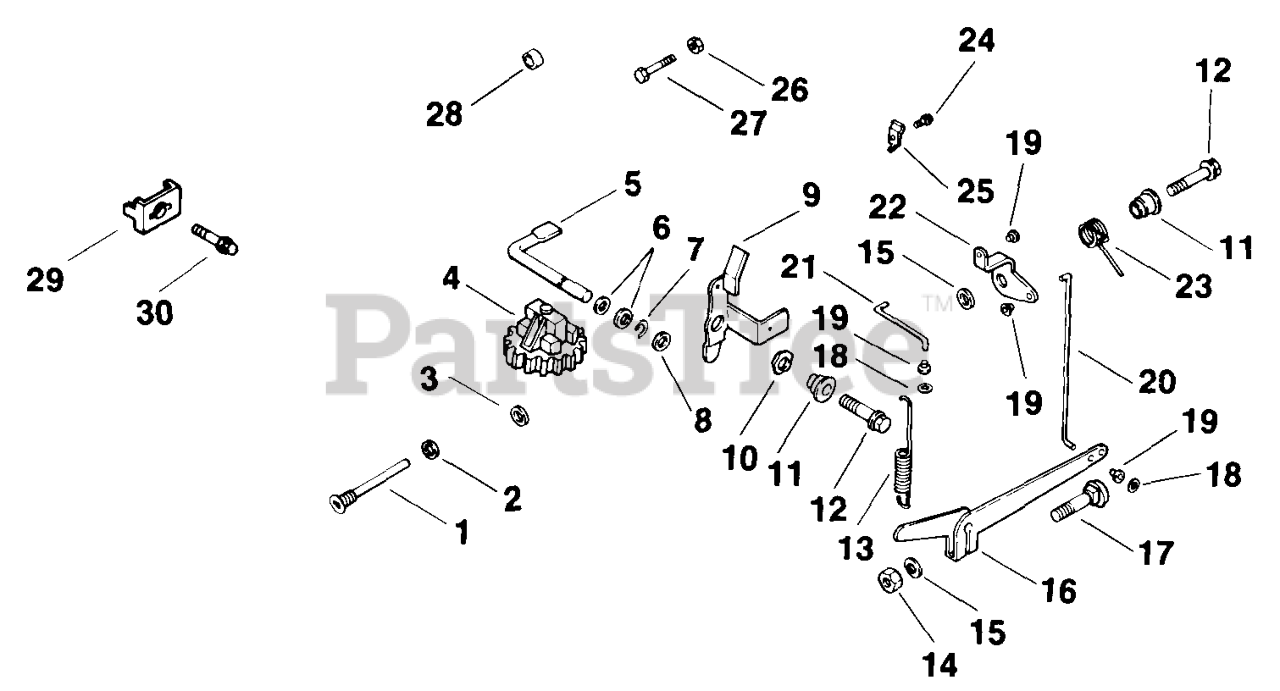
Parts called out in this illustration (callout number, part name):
1	Pin, Governor Stop
2	Washer, Plain 1/4"
3	Washer, Governor Gear Thrust
4	Kit, Governor Gear
5	Shaft, Governor Cross
6	Washer, Plain 1/4"
7	Retainer, Governor
8	Washer, Plain 1/4"
9	Lever, Speed Control
10	Washer, Tension
11	Bushing, Lever
12	Screw, Hex. Wash. Hd. 1/4-20x1"
13	Spring, Governor
14	Nut, Hex. 1/4-20
15	Washer, Plain 1/4"
16	Arm, Governor
17	Bolt, R.H. Sq. Neck. 1/4-20x1"
18	Ring, Retaining
19	Bushing, Linkage Retaining
20	Linkage, Governor
21	Linkage, Throttle
22	Lever, Throttle
23	Spring, Torsion
24	Screw, Hex. Wash. Hd. 10-24x3/8"
26	Nut, Hex. 10-32
27	Screw, Ind. Hex. Hd. 10-32x1-3/4"
28	Spacer 1/4" I.D. X 3/8" O.D.
30	Screw, Hex. Wash. Hd. 1/4-20x5/8"
